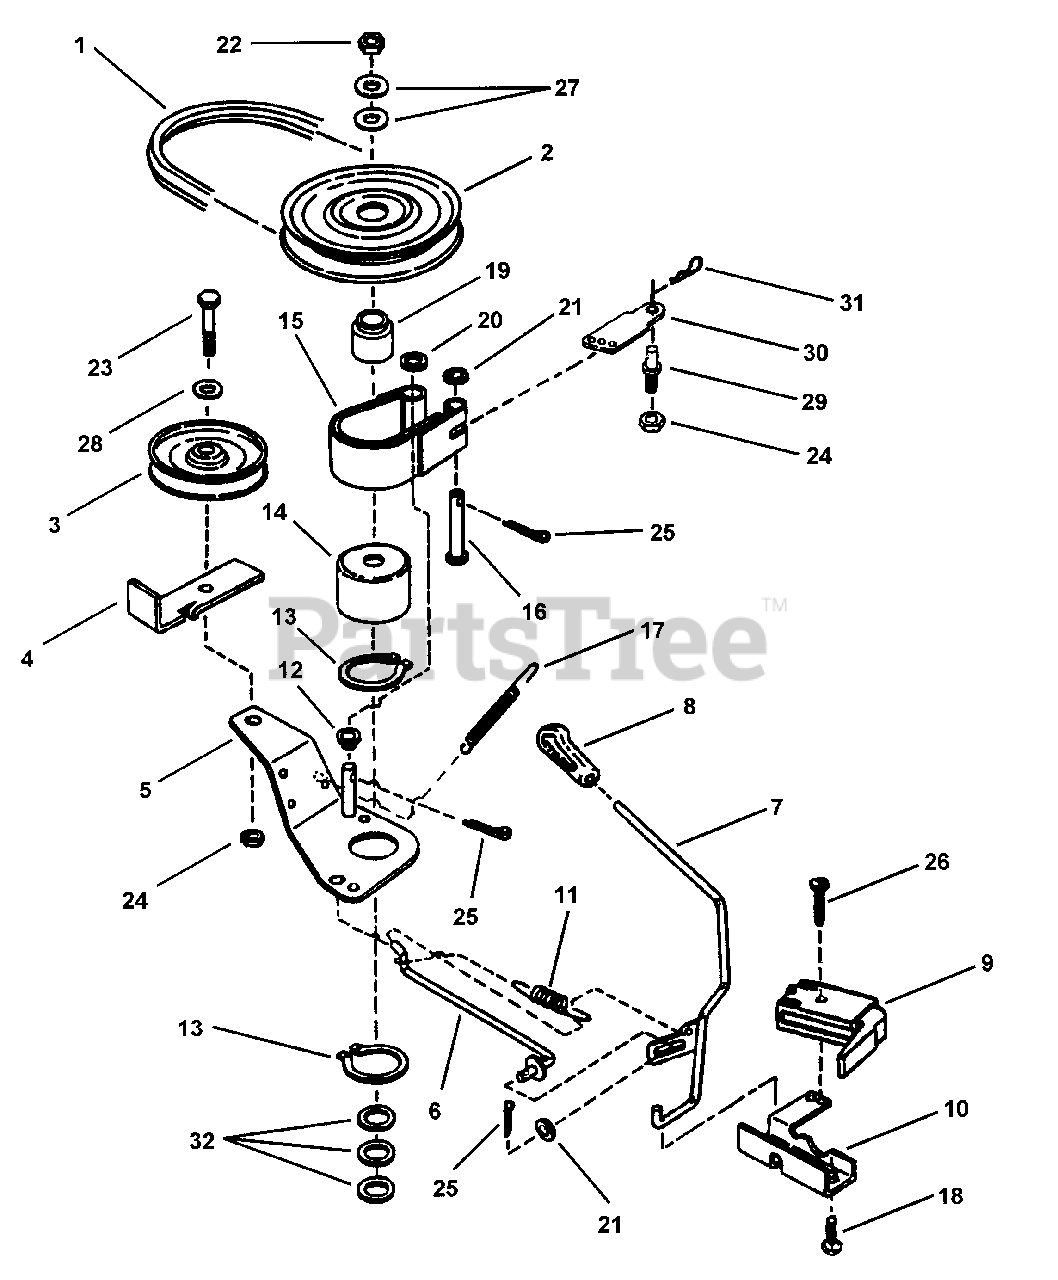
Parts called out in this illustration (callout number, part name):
1	BELT, Drive (72.75 AA Section)
2	PULLEY, Spindle
3	PULLEY, Idler
4	RESTRICTOR, Belt
5	ARM, Idler (weldment)
6	ROD, Idler
7	HANDLE, Blade Lever (On-Off) (Weldment)
8	GRIP, Handle
9	SWITCH, Deck Interlock
10	MOUNT, Handle
11	SPRING, Blade Handle
12	SPACER
13	RING, 2" External Retaining
14	DRUM, Brake
15	BAND, Brake
16	PIN, 1/4 x 1-5/8" Clevis
18	SCREW, 1/4-20 x 5/8" Hex Washer Self-Tap
19	HUB, Pulley
20	WASHER, 3/8" Flat
21	WASHER, 1/4" Flat
22	NUT, 3/4-16 Hex Jam
23	SCREW, 3/8-16 x 1-1/2" Hex Head Cap, Grade 5
24	NUT, 3/8-16 Hex Nyloc
25	PIN, 3/32 x 3/4" Cotter
26	SCREW, #10-32 x 1" Hex Washer Self-Tap
27	WASHER, 49/64 x 1-1/2" Flat
28	WASHER, 3/8" Flat
29	STUD (3/8-24 Thread)
30	BRACKET, Brake Anchor
31	HAIRPIN, 5/16 x 1-3/16"
32	WASHER, 3/4" Flat
